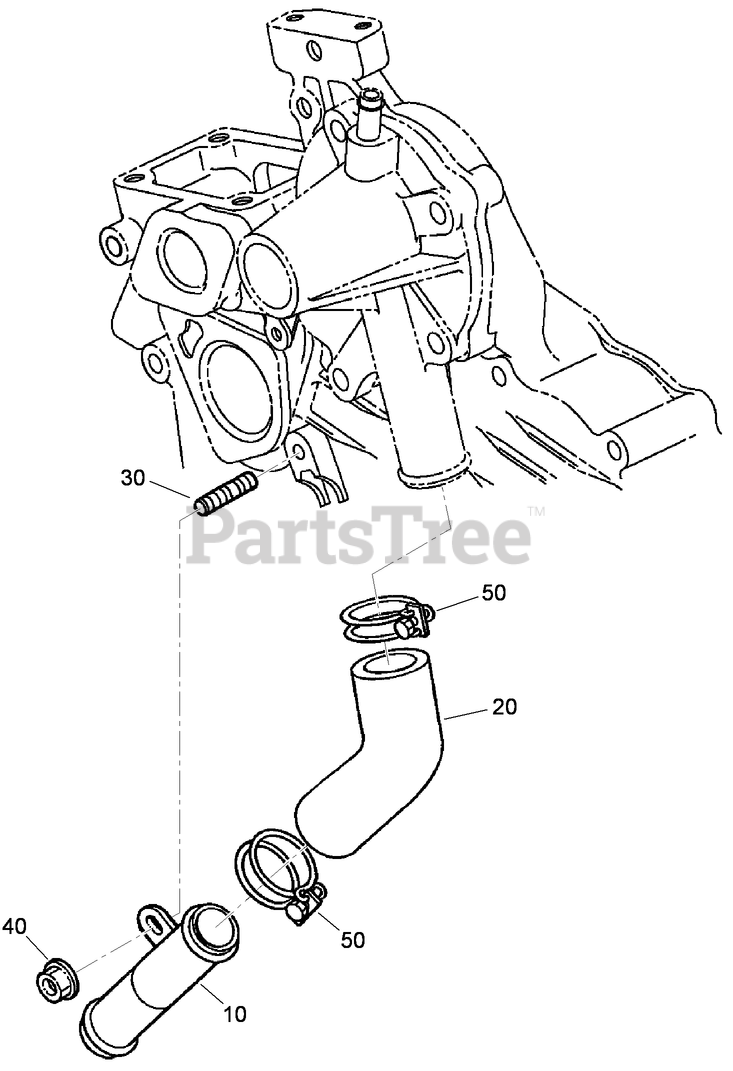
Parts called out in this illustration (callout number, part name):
10	PIPE-WATER
20	PIPE-WATER
40	NUT-FLANGE
50	BAND-PIPE
